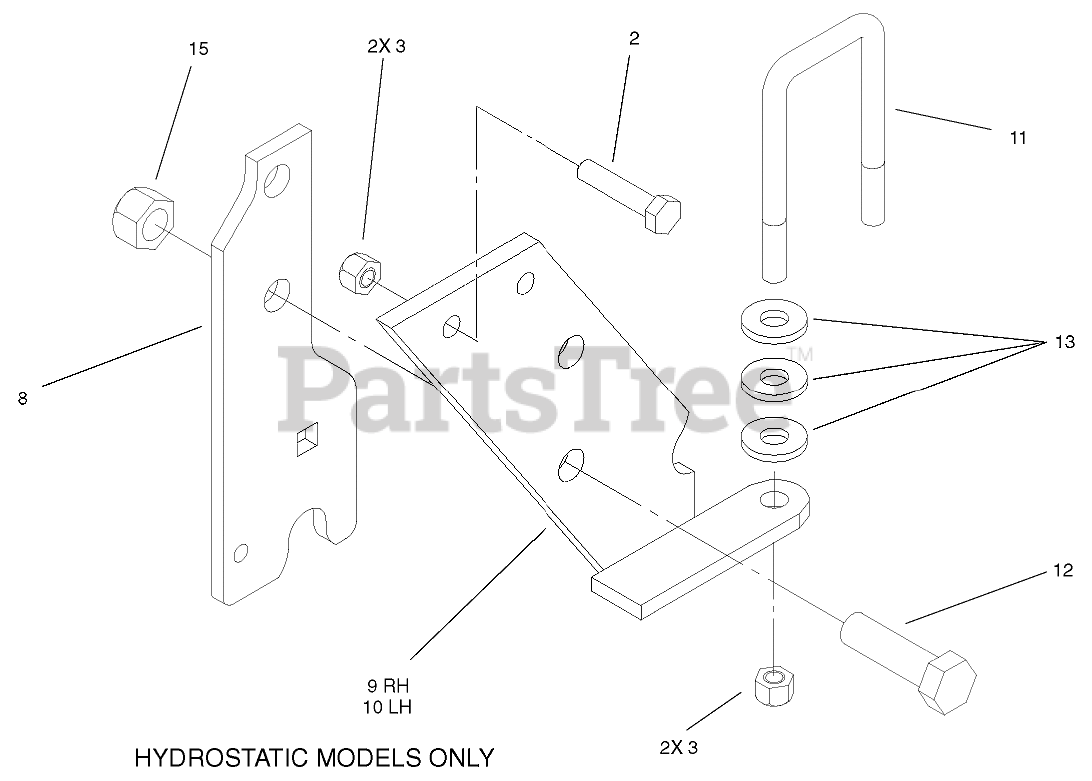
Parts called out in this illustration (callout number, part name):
2	SCREW-HH
3	NUT-LOCK, NI
8	BRACKET-HITCH
9	PLATE-HITCH
10	PLATE-HITCH
11	U-BOLT
12	SCREW-HH
13	WASHER-SPACER
15	NUT-LOCK, NI
